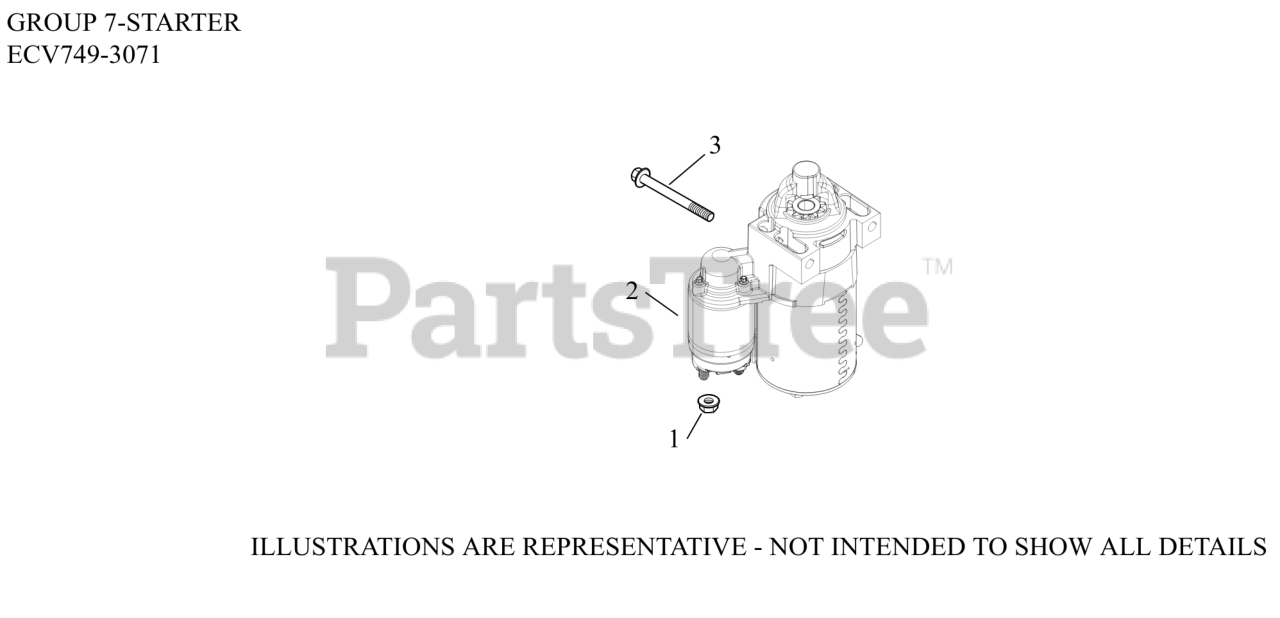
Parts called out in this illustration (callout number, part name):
1	NUT, FLG M8X1.25
2	STARTER, SOLENOID SHIFT
3	SCREW, FLG M8X1.25X80
